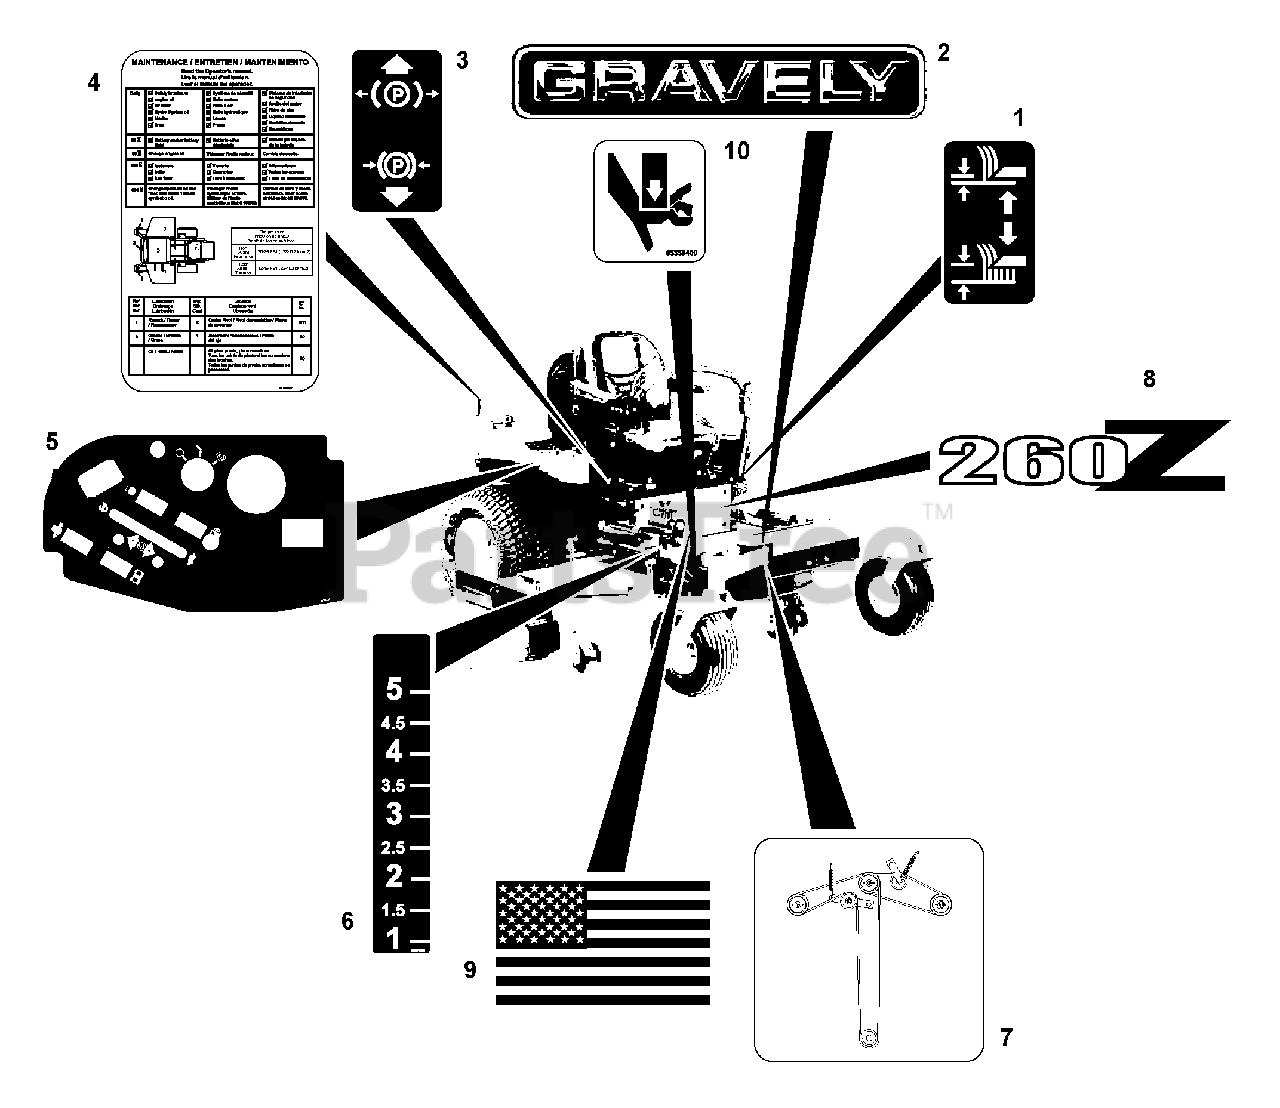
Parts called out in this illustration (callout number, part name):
1	Decal, Lift Lever
2	Decal, 15" Gravely Logo
3	Decal, Parking Brake Lever
4	Decal, Service Instructions
5	Decal, Diesel Control Panel
6	Decal, Height of Cut
7	Decal, Belt Diagram
8	Decal, PM-252Z
8	Decal, PM-260Z
8	Decal, PM-272Z
9	Decal, American Flag
10	Decal, Pinch Point
